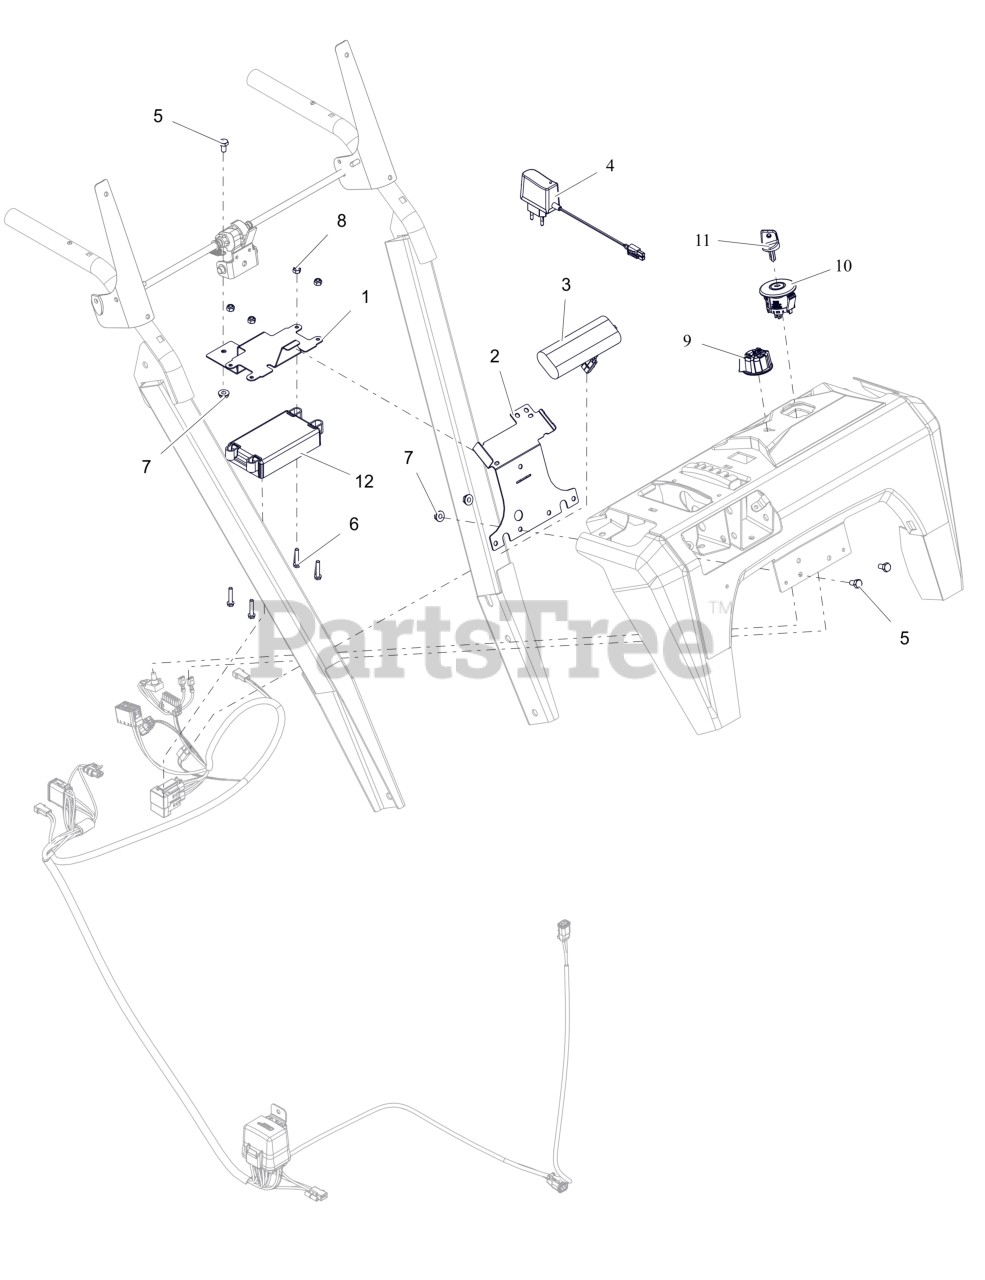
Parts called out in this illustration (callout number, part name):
1	BRACKET, ENGINE EFI-LCT LOWER
2	BRACKET, ENGINE EFI-LCT UPPER
3	BATTERY, SNOW EFI - 7.2V
4	CHARGER, BATTERY-EFI 7.2V (EU)
5	BLT,HEX .25-20X.50 G5 ZCC
6	BLT, HWH #10-24X1.00 ZCC
7	NUT-LK-TOP-FLG .250-20 GF ZCC
8	NUT-LK-NYL #10-24 G2 ZCC
9	KNOB- CONTROL EFI
10	IGNITION SWITCH ASM - 2 POS
11	KEY- IGNITION
12	ECU SERVICE LCT/CSI - 420CC
